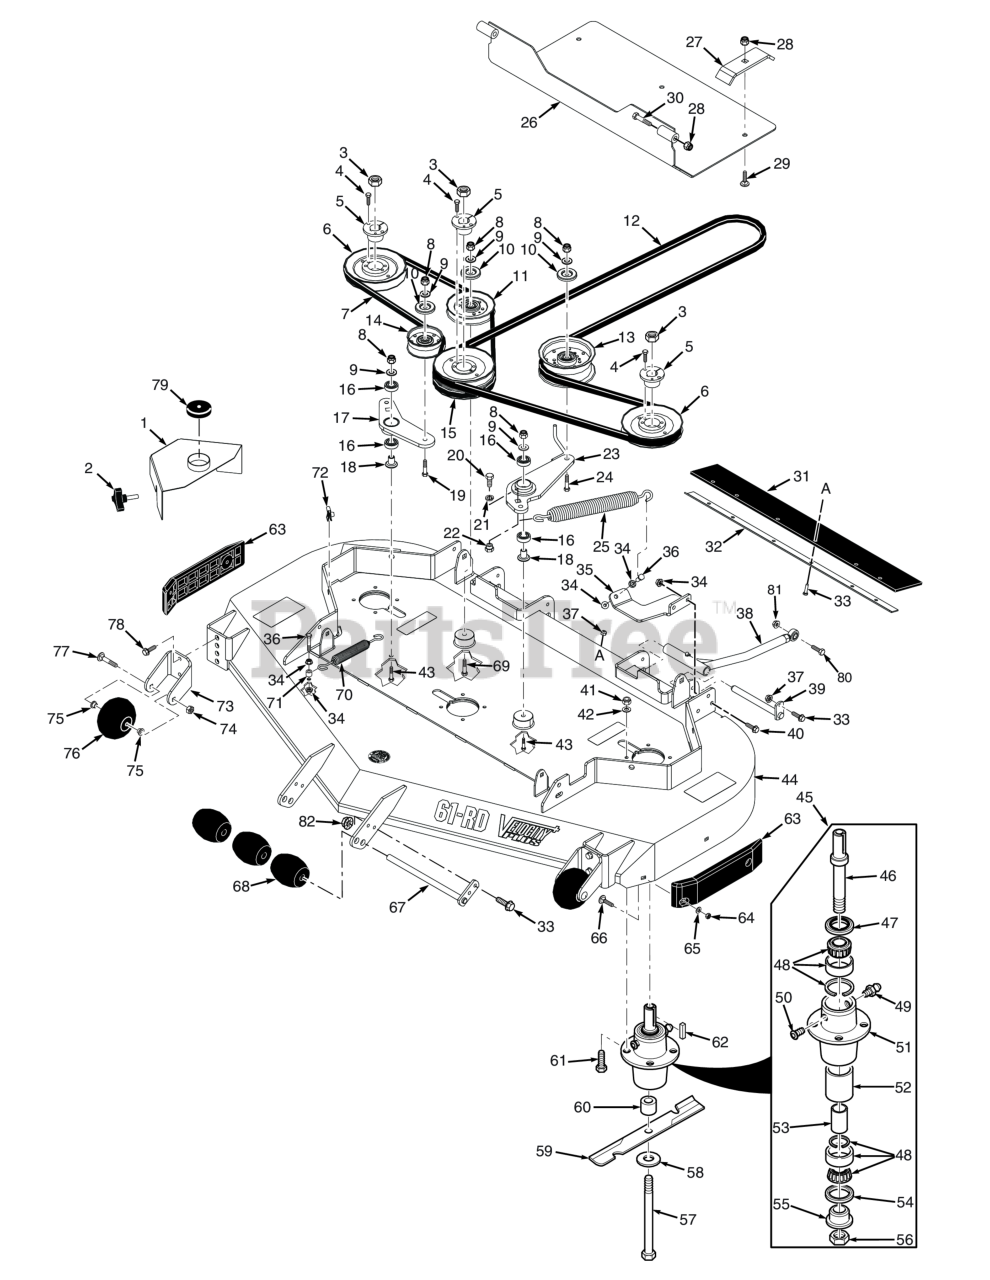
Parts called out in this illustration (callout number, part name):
1	Belt Cover, LH (INCL 85)
2	Knob, w/stud 3/8-16 x 1-1/4"
3	Hex Locknut, Elastic Stop, 3/8-16
4	Bolt, Hex Head 1/4-20 x 1" Grade 8 Black
5	Hub, Tapered 1-1/8" Bore
6	Pulley, Tapered Bore 6.33" Dia.
7	Belt, Deck Drive R.H.
8	HEX NUT, ELASTIC STOP LOCK, 3/8-16
9	Flatwasher, 3/8 (.391 x .938 x .105 HD) Grade 8
10	Quick Pin, 5/16" Dia.
11	IDLER PULLEY, "V" GROOVE
12	Belt, Cutter Deck Drive - Cat
13	Pulley, Idler 5" Dia.
14	Pulley, 3-1/2" Dia.
15	Pulley, Double Groove 6.33" Dia.
16	BEARINGS, BALL, NEUTRAL RETURN
17	ldler Arm Assembly, R.H. Drive
18	Pivot, Idler Short
19	Capscrew, Hex Head 3/8-16 x 2-1/2"
20	Bolt, Hex Head 7/16-14 x 1"
21	Lockwasher, 7/16� Spring
22	Boss, Spring Anchor - LH
23	Idler Arm
24	Bolt, Hex Head 3/8-16 x 3" - 52"
25	Spring, L.H. Deck Drive
26	Weldment, Debris Shield
27	Mounting Bracket, Shield
28	HEX NUT, ELASTIC STOP LOCK, 5/16-18
29	Bolt, Carriage 5/16-18 x 1-1/2"
30	Bolt, Hex Head, 5/16-18 x 2.75 Zinc.
31	Pad, Rubber
32	Retaining Plate, Pad
33	Bolt, Heax Head 5/16-18 x 1" (48V / 52V)
34	NUT, 3/8-16 SERRATED FLANGE HEX HEAD
35	Spring Mount, SMCZ
36	Bolt, Hex Head 3/8-16 x 1-1/2" Grade 8 Black
37	HEX NUT, ELASTIC STOP LOCK, 5/16-18
38	Pusharm Assembly, LH
39	Shaft Weldment, Pusharm
40	Bolt, Hex Head, 3/8-16 x 1 Gr. 5
41	Lock Nut, 5/16-18 Elastic Stop Grade 8
42	Lockwasher, 5/16 (.317 x .586 x .078) Helical Spring
43	Bolt, Hex Head 3/8-16 x 3" - 52"
44	Cutter Deck Assembly w/Decals SCZII-61RD
45	Cutter Spindle Assembly
46	Spindle Shaft, Tapered Brng
47	SEAL, 2.00 O.D. X 1.50 BORE
48	Tapered Bearing Set (Two Bearings W/Race)
49	GREASE FITTING, STR. 1/4-28 SELF TAP.
50	RELIEF FITTING, TAPERED BEARING SPINDLE
51	Housing, Spindle
52	Spacer, Outside, Cutter Spindle
53	SLEEVE, CUTTER SPINDLE
54	Seal, 2.00" O.D. x 1.625" Bore
55	SPINDLE BUSHING, BOTTOM
56	Nut , Spec ial 1 -1/ 1 6 - 1 8
57	BOLT, HEX HEAD, 5/8-11 X 9-1/2 GR.5
58	Flatwasher, 5/8-.688 x 1-3/4 x .134 HD
59	Cutter Blade, 21" (35BV & 37BV-EFI)
60	Spacer, Spindle Bottom
61	Bolt, Hex Head 5/16-18 x 1-3/4" Grade 8
62	Key, 1/4 x 1/4 x 2.0"
63	Pad, Deck Wear
64	Nut, Center Lock, 5/16-18(32)
65	Flatwasher, 5/16-.344 x .688 x .065 (48V / 52V)
66	Bolt, 5/16-18 x .75 RHSN Carriage
67	Shaft Weldment, Guide Roller
68	Wheel, Anti-Scalp
69	Bolt, Hex Head 3/8-16 x 2-1/4" - 61"
70	Spring, RH Deck Drive
71	SPACER, IDLER
72	U-Nut, 3/8-16
73	Bracket, Anti-Scalp Wheel
74	Bolt, Hex Head 3/8-16 x 1" Ser. Flg.
75	Bushing, .376" I.D. Oilite
76	Bolt, Carriage 3/8-16 x 4"
77	Bolt, Hex Head 3/8-16 x 3-1/2"
78	Capscrew, 3/8-16 x 1.0" Serrated Flange Hex Hd
81	Nut, Center Lock 5/8-11
82	Nut, Flange Head Elastic Stop 5/16-18
